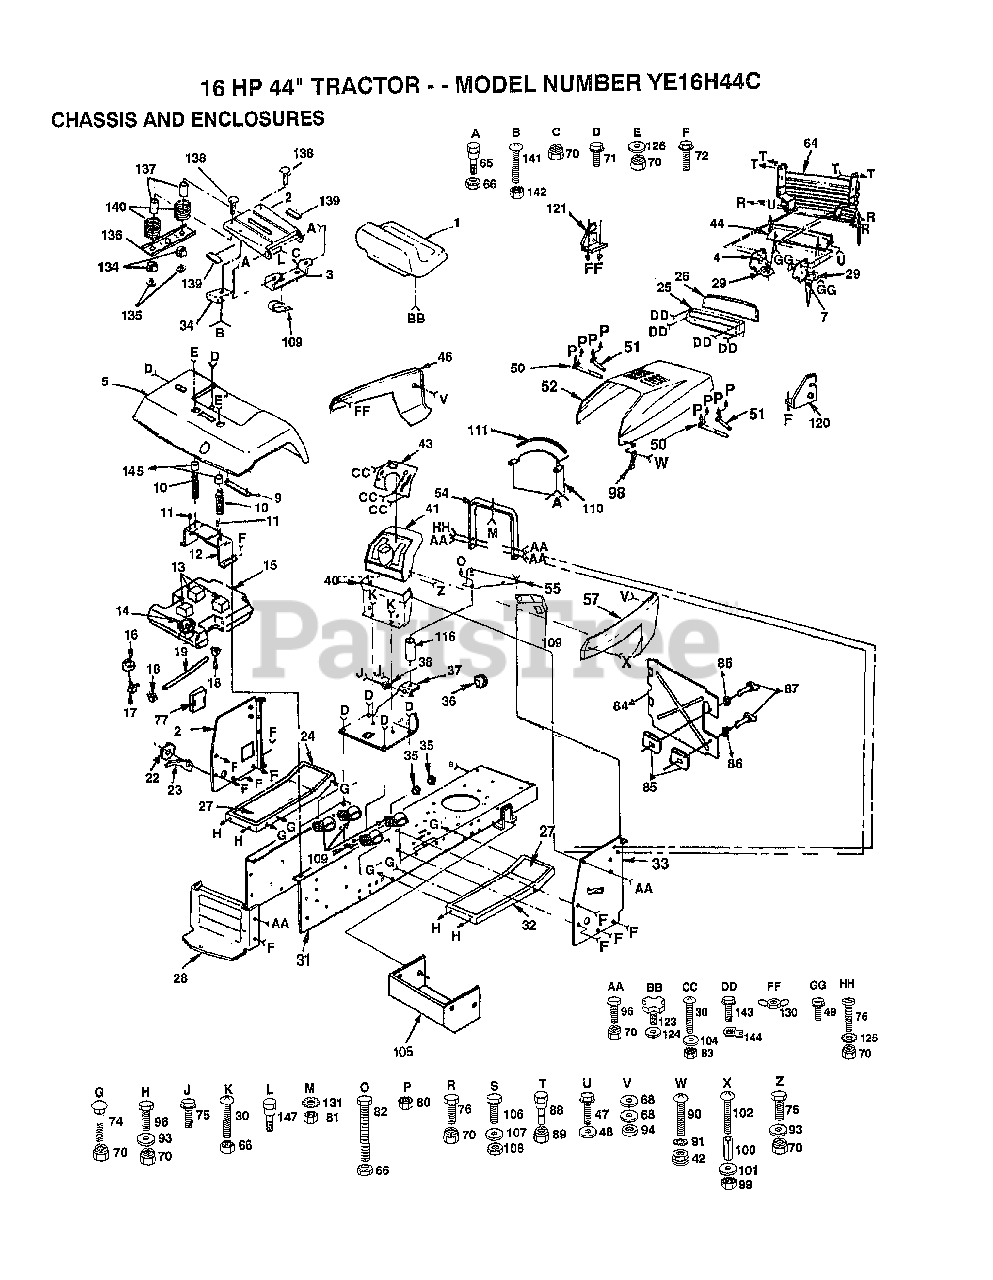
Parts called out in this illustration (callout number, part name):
4	SUPPORT LH YTH
5	FENDER
7	SUPPORT RH YTH
10	SPRING COMPRESSIO
11	NUT-PUSH YT
13	PAD-SPACER T
16	BUSHING OUTLET T
17	FUEL TANK STEM GT
18	HOSE CLAMP
21	PANEL DASH LH
22	WASHER T
26	LENS LT
27	PAD FOOTREST T
28	DRAWBAR LT/YT
29	WASHER
30	SCREW
33	DASH PANEL RH
36	SNAP BUSHING T
40	LOWER DASH
42	WELDNUT
47	SCREW
48	WASHER
49	SCREW
54	SUPPORT ASS'Y
57	"PANEL,SIDE RH "
68	WASHER PM
71	SCREW LT
72	SCREW
74	BOLT
76	BOLT
77	COVER ACCESS
80	NUT
82	BOLT
85	RECEPTACLE LT
86	RETAINER LT
87	STUD.1/4.TURN
90	SCREW
91	LOCKWASHER
93	WASHER
98	HOOD LATCH T
100	SPACER LT
101	WASHER
102	SCREW
104	WASHER
106	BOLT LT
107	WASHER
108	"NUT,SELF RETAININ"
109	CLIP T
110	VERTICAL BAFFLE
111	FOAM STRIP T
116	SPACER
120	SUPPORT RH YTH
121	SUPPORT LH YTH
123	"KNOB 1/2"" YT"
124	WASHER
125	LOCKWASHER
126	WASHER
134	BUSHING
136	BRKT SWITCH
137	SPACER SPLIT
139	STRIP FORM
140	SPRING COMPRESSED
142	"NUT,KEPS"
144	"""J"" FASTENER LT"
145	CAP SPRING
147	"BOLT,SHOULDER"
